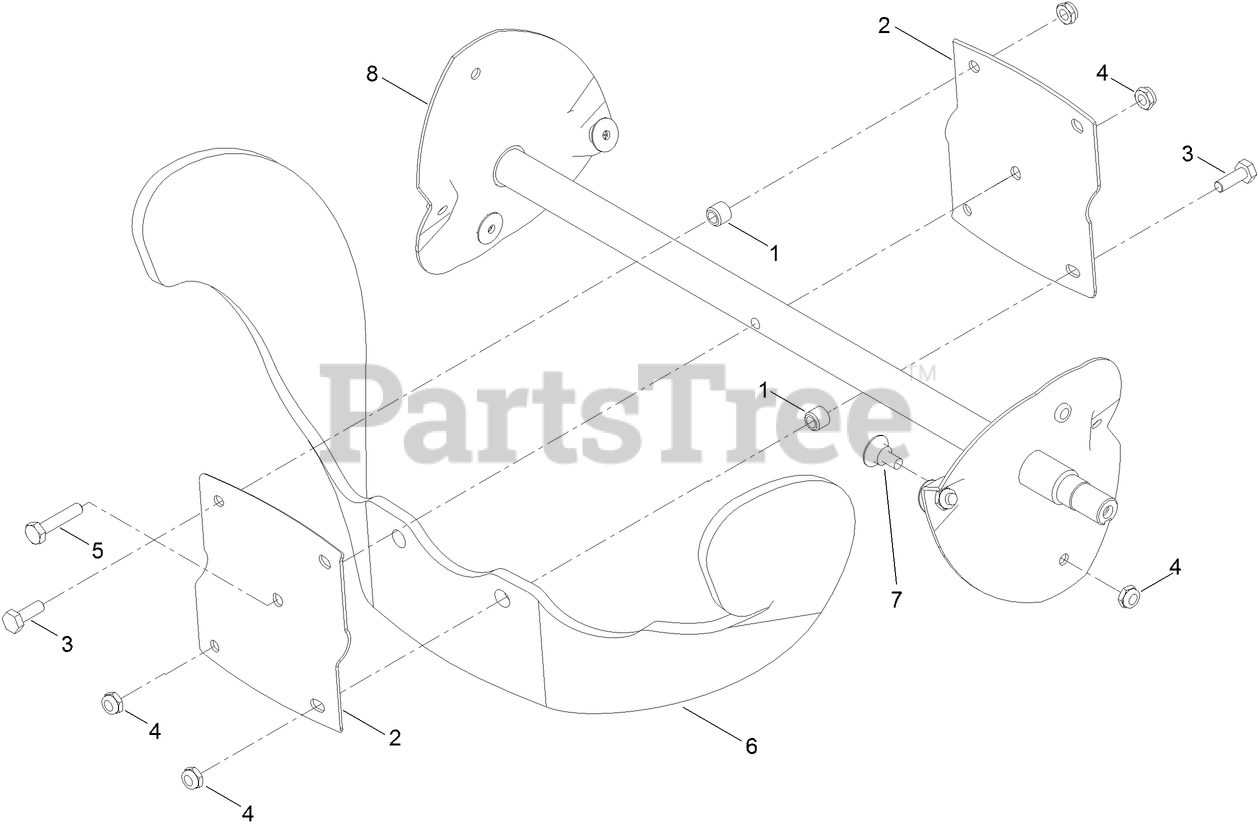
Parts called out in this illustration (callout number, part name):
1	SPACER-BLADE, ROTOR
2	HALF-ROTOR
3	SCREW-HH
4	NUT-LOCK, NI
5	SCREW-HH
6	BLADE-ROTOR
8	ROTOR KIT
